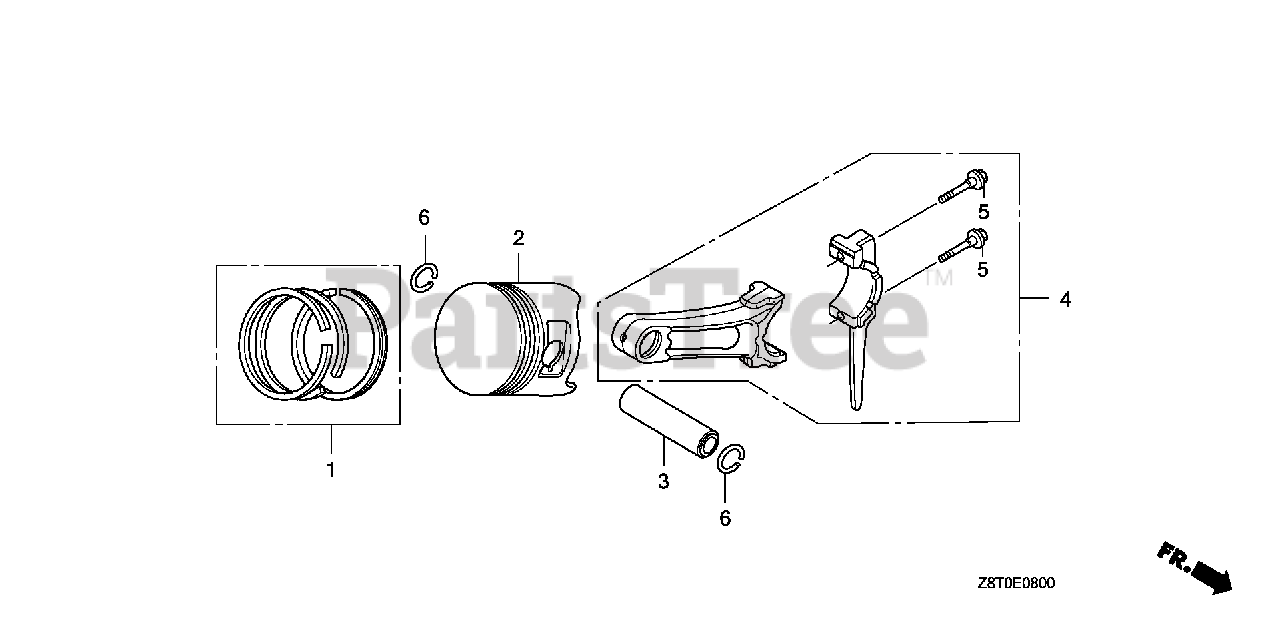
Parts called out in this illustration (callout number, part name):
1	RING SET, PISTON (STD) (TEIKOKU)
1	RING SET, PISTON (0.25) (TEIKOKU)
1	RING SET, PISTON (0.50) (TEIKOKU)
1	RING SET, PISTON (0.75) (TEIKOKU)
2	PISTON (STD)
2	PISTON (0.25)
2	PISTON (0.50)
2	PISTON (0.75)
3	PIN, PISTON
4	ROD ASSY., CONNECTING (STD)
4	ROD ASSY., CONNECTING (0.25 LOWER SIZE)
5	BOLT, CONNECTING ROD
6	CLIP, PISTON PIN (20MM)
